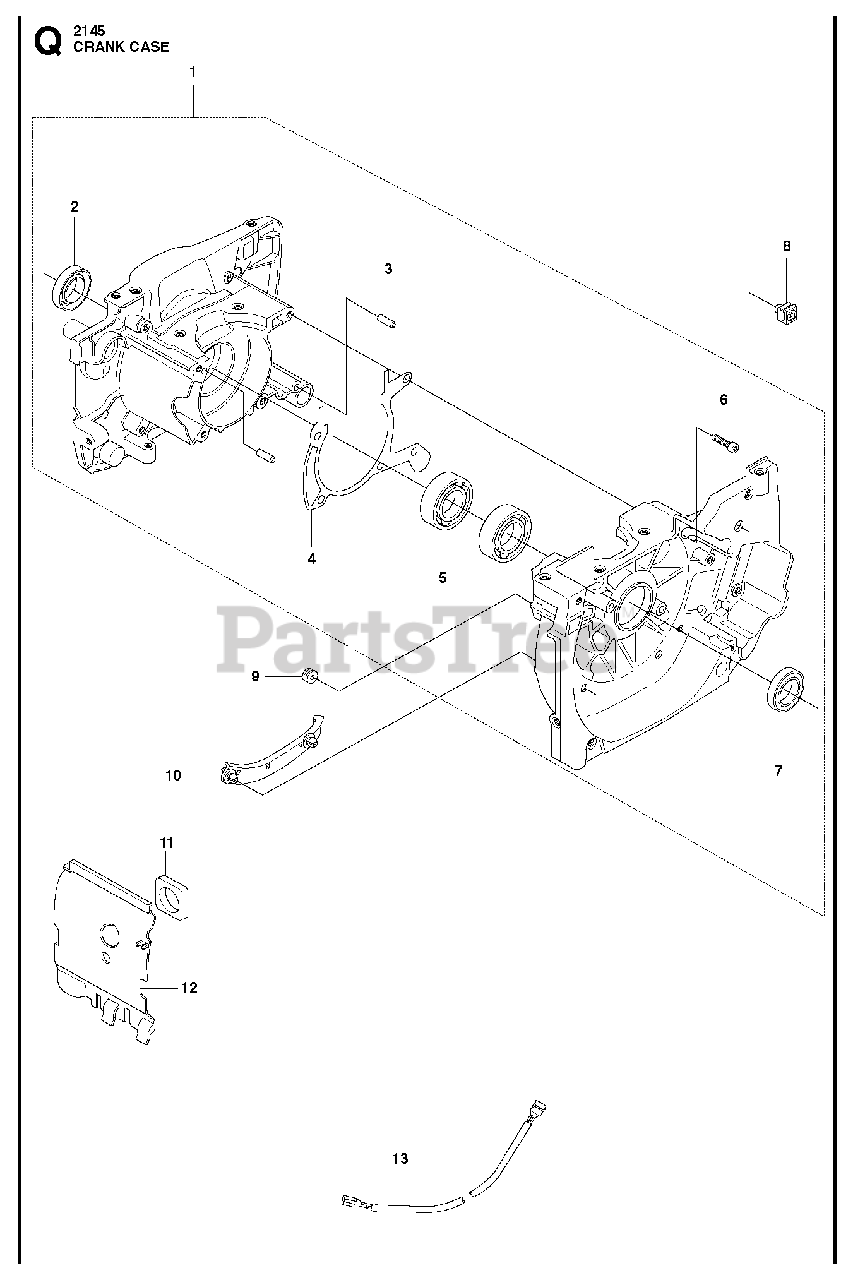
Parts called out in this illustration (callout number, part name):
1	CRANKCASE
2	SEALING RING
3	PIN 5X14
4	GASKET
5	BALL BEARING-6202-C3 SKF
6	SCREW MC6S 5X20
7	SEAL RING
8	CABLE SOCKET
9	FUEL TANK BUSHING
11	SEAL
12	AIR CONDUCTOR
13	SHORTING LEAD
